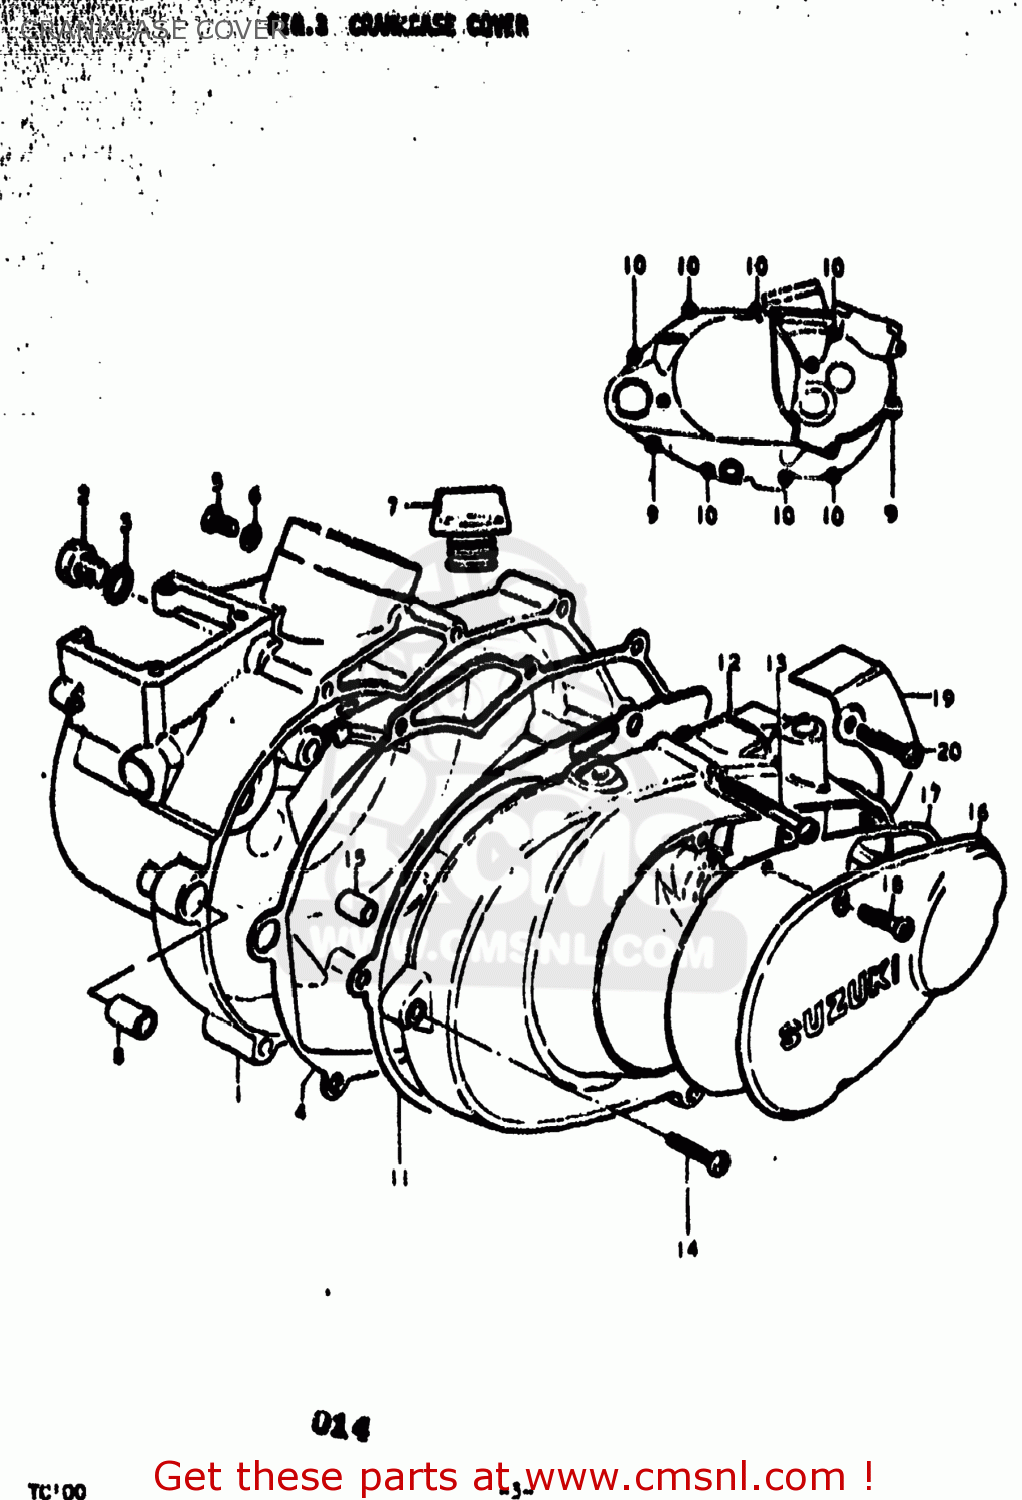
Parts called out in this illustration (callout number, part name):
1	COVER,CLUTCH
2	PLUG
3	GASKET(14X19.2X2) (NAS)
4	GASKET,CLUTCH COVER (MCA)
5	SCREW(6X10)
6	GASKET(6.2X11X1) (NAS)
7	PLUG
8	PIN
9	SCREW
10	SCREW
11	GASKET,MAGNETO COVER (MCA)
12	COVER
13	SCREW
14	SCREW
15	PIN
16	CAP,MAGNETO INSPECTION
17	GASKET (MCA)
18	SCREW
19	COVER,SPROCKET
20	SCREW 6X12
